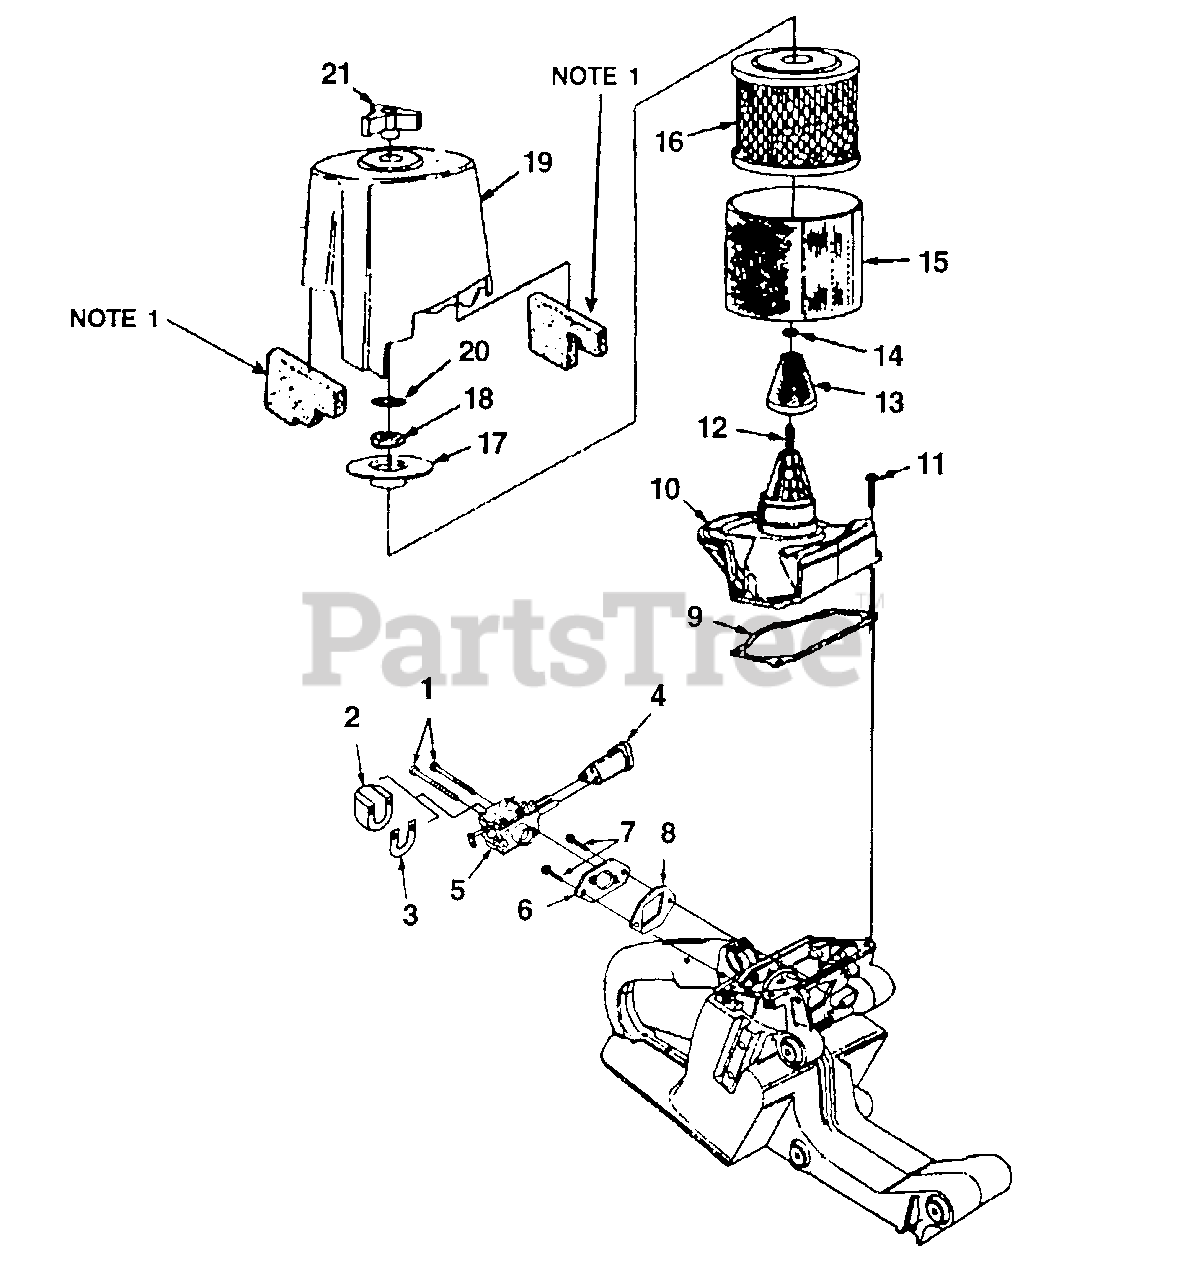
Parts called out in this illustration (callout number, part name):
1	SCREW - Hex Cap (10-14 X 2")
2	SHIELD - Carburetor
3	GASKET - Carburetor Shield
4	GROMMET
5	CARBURETOR
6	ADAPTER - Carburetor
7	SCREW - Torx Truss (10-24 X 1/2")
8	GASKET - Carburetor
9	GASKET - Carb Chamber
10	COVER - Carb Chamber
11	SCREW - Pan Hd (8-32 X 5/8")
12	BOLT
13	FILTER - Air
14	"O" Ring
15	FELT PREFILTER
16	ELEMENT - Air Filter
17	AIR FILTER ELEMENT COVER
18	NUT Hex (5/16-18)
19	FILTER COVER
21	RETAINING RING
